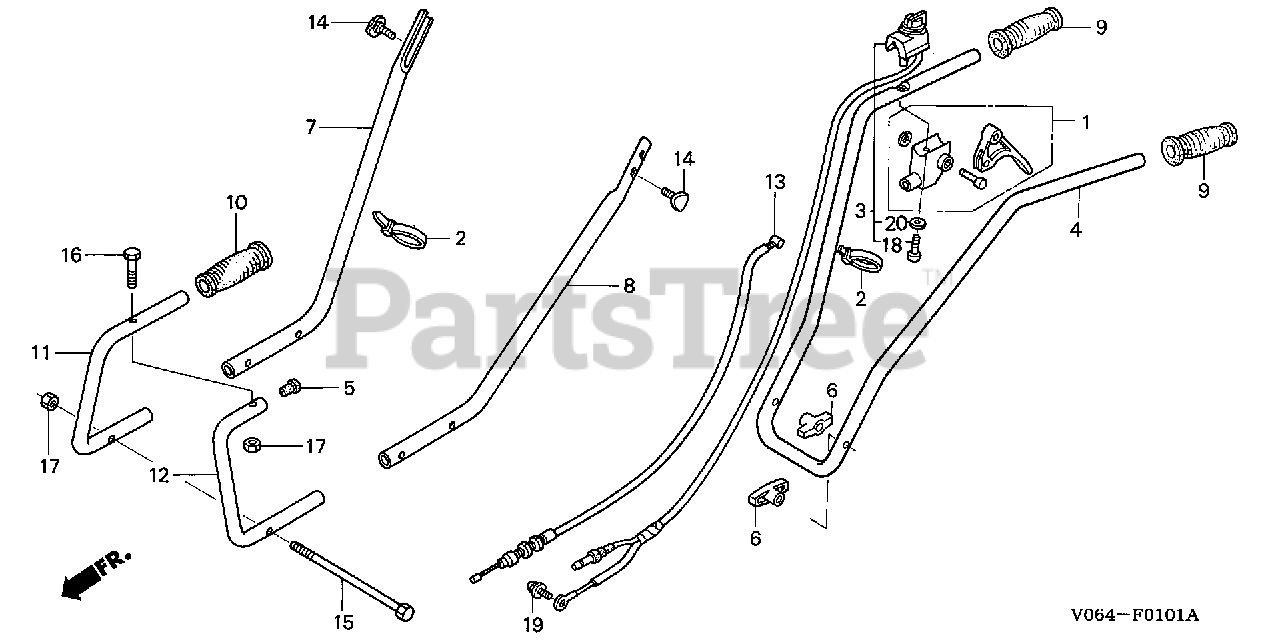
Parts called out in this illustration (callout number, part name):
1	LEVER, THROTTLE
2	TIE, CABLE
3	SWITCH ASSY., ENGINE STOP
4	HANDLE (UPPER)
5	CAP, HANDLE (LOWER)
6	GRIP, HANDLE JOINT
7	HANDLE, R. (LOWER)
8	HANDLE, L. (LOWER)
9	GRIP, HANDLE
10	GRIP, CARRY
11	HANDLE, R. CARRY
12	HANDLE, L. CARRY
13	CABLE, MAIN CLUTCH
14	BOLT, HANDLE JOINT
15	SCREW (1/4-20X6)
16	SCREW (1/4-20X2)
17	NUT (1/4-20)
18	SCREW, PAN (3X12)
19	SCREW-WASHER (5X12)
20	WASHER, SPRING (3MM)
